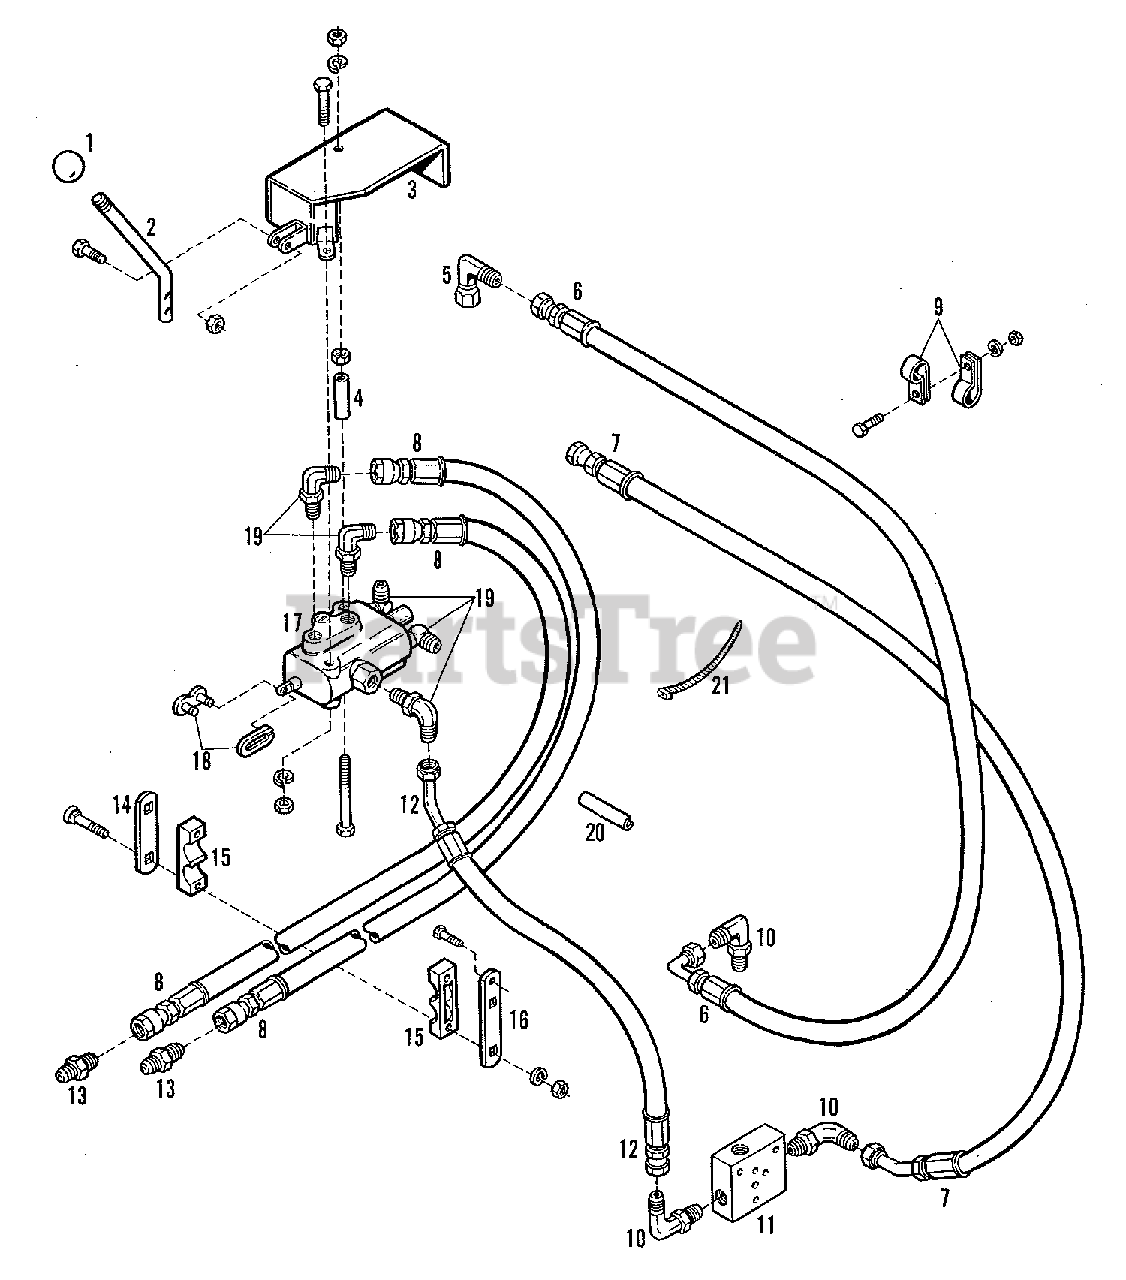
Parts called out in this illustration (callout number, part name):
2	ROD, Control
2	CAPSCREW, 1/4NC x 1-1/4
2	NUT, Lock, 1/4NC
3	COVER ASSEMBLY
3	CAPSCREW, 1/4NC x 2
3	LOCKWASHER, 1/4
5	ELBOW, Swivel Nut, 3/8 Tube
6	HOSE ASSEMBLY
7	HOSE ASSEMBLY
8	HOSE ASSEMBLY, Valve to Cylinder
9	CLAMP, Hose
9	CAPSCREW, 5/16NC x 1
9	LOCKWASHER, 5/16
9	NUT, 5/16NC
10	ELBOW, 90 Degrees x 1/2
11	MANIFOLD
11	CAPSCREW, M8 x 1-1/4 x 70MM
11	LOCKWASHER, M8
12	HOSE ASSEMBLY
13	CONNECTOR, Male
14	BOLT, Carriage, 5/16NC x 2
14	LOCKWASHER, 5/16
14	NUT, 5/16NC
16	CAPSCREW, M8 x 1-1/4 x 20MM
17	VALVE ASSEMBLY, Control
17	CAPSCREW, 1/4NC x 4
17	LOCKWASHER, 1/4
18	LINK, Connecting
19	ELBOW, 90 Degrees x 3/8
20	MOULDING (3" Long)
20	MOULDING (2-1/2" Long)
21	TIE, Plastic, Black
